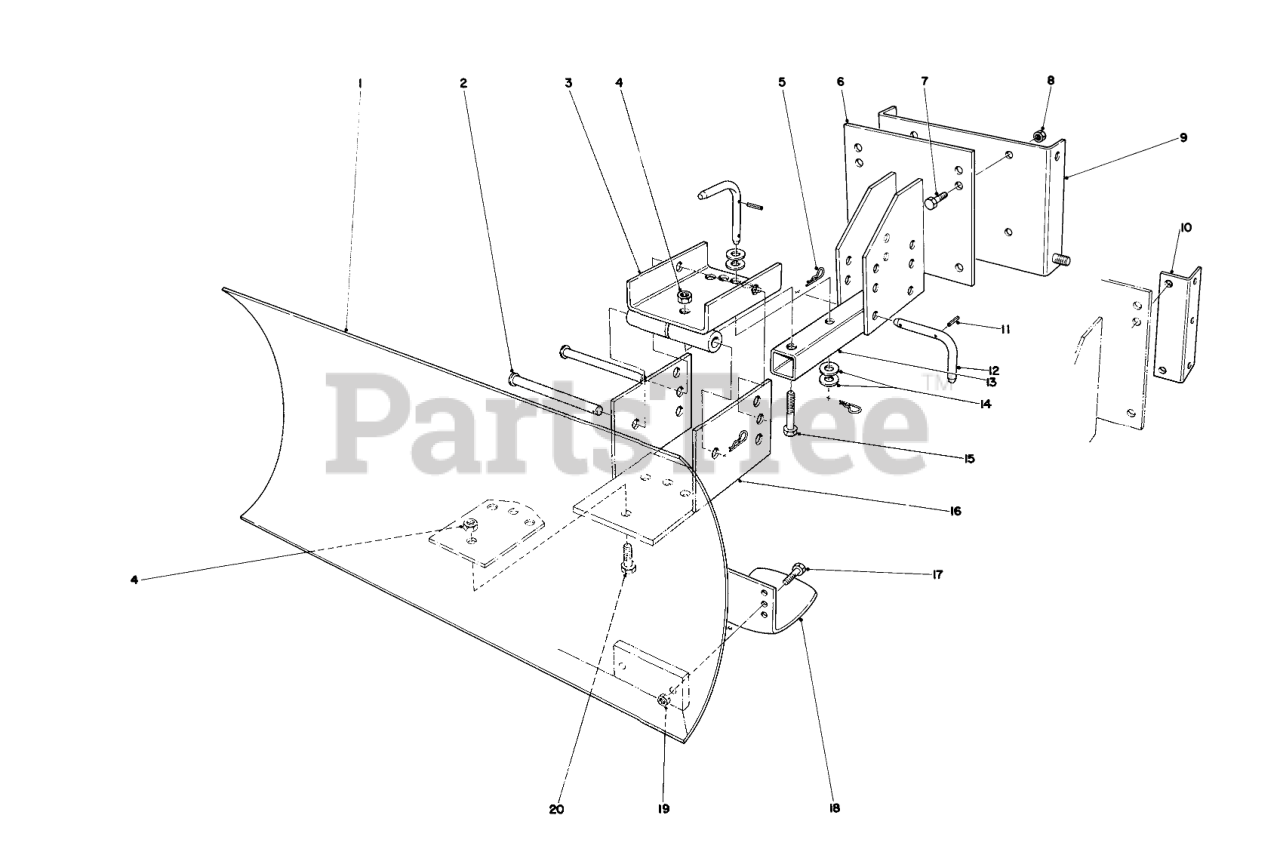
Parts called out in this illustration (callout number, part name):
1	Blade
2	PIN-CLEVIS
3	Swivel Bracket
4	1/2-13 CONELOCK NUT
5	PIN-HAIR
6	Mounting Plate
7	SCREW-HH
8	NUT-LOCK, CONE
9	Mounting Plate (Used with 826 & 1132 Units only)
10	Mounting Rail (used with 421 units only)
11	PIN-SPRING
12	Pivot Pin (Incl. Ref. #11)
13	Blade Tongue
14	WASHER-FLAT
15	SCREW-HH
16	Blade Adjustment
17	SCREW-HH
19	NUT-LOCK, CONE
20	SCREW-HH
